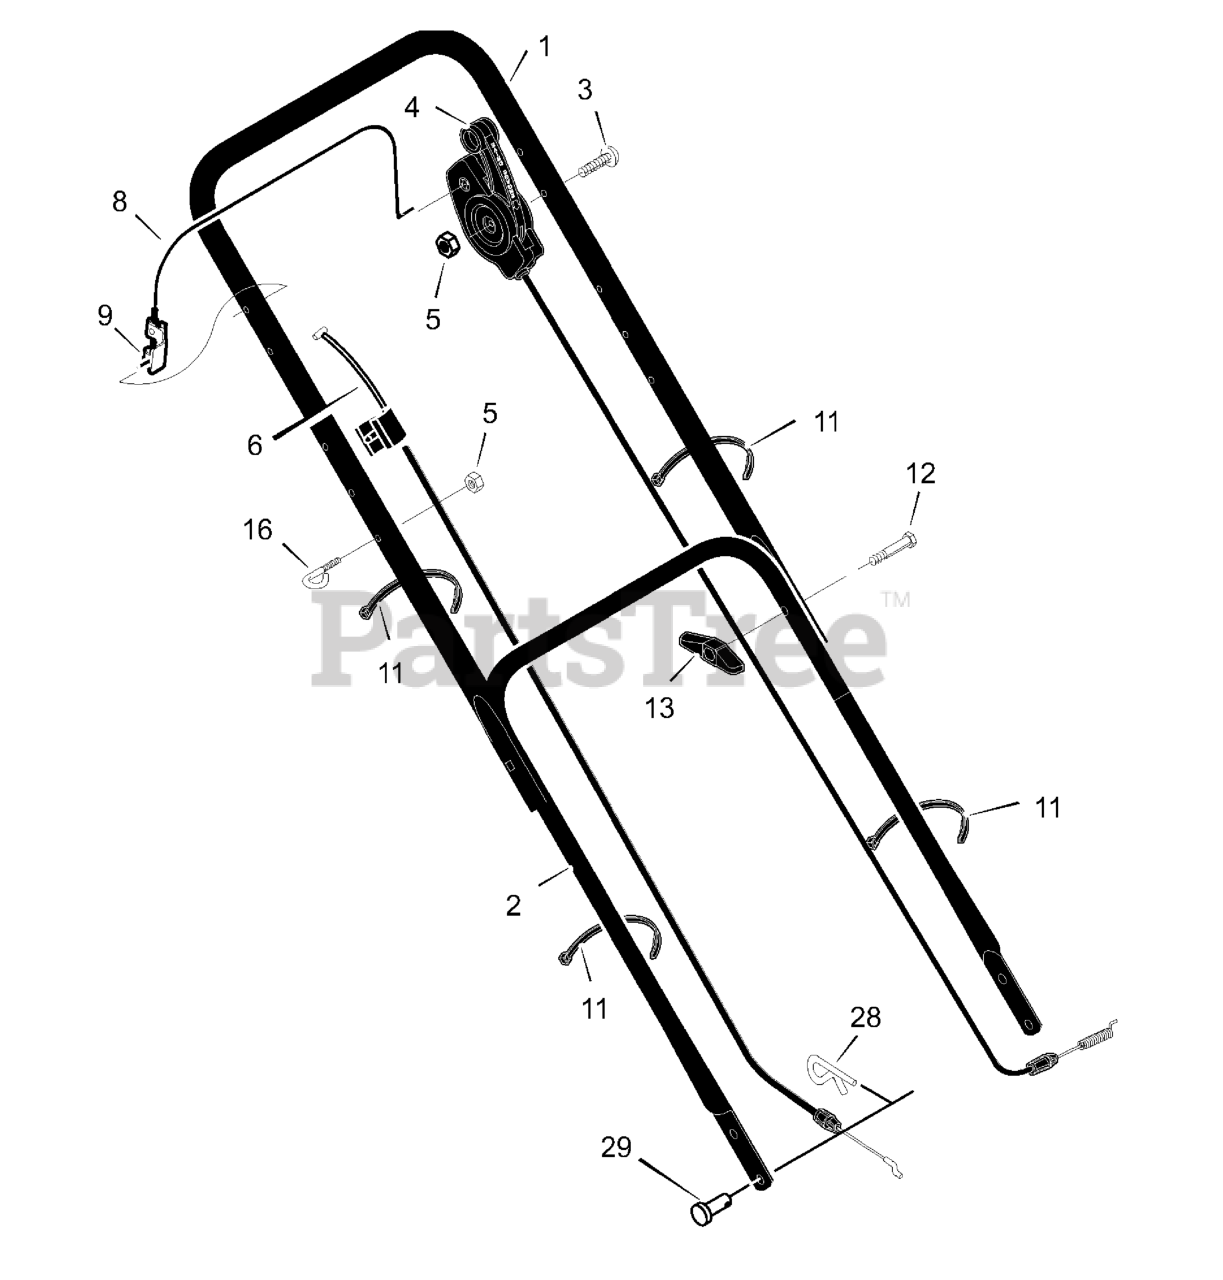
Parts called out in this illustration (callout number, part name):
1	Handle, Upper (Black)
2	Handle, Lower (Black)
4	Control, Drive
5	Locknut
6	Cable, Stop
8	Lever, Stop
9	Bracket, Stop Lever
11	Fastener, Cable
13	Knob
16	Guide, Rope
28	Hairpin
29	Pin, Clevis
